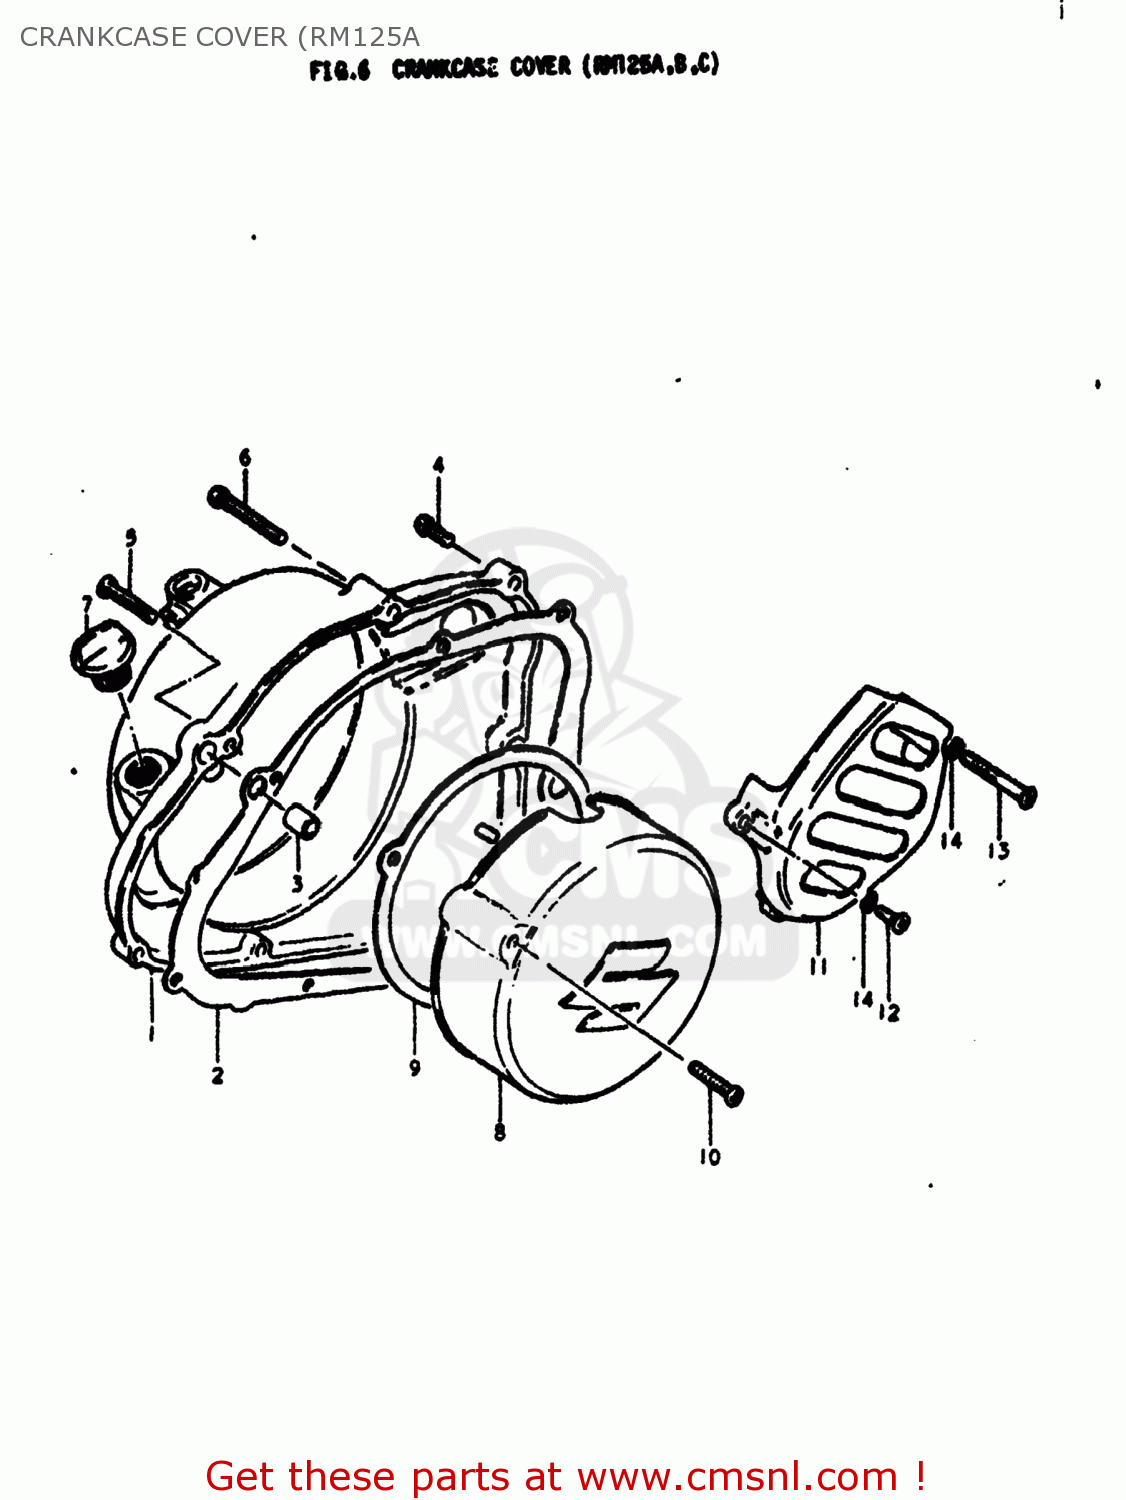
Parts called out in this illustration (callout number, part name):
1	COVER,CLUTCH
2	GASKET,CLUTCH COVER (AS (MCA)
3	PIN
4	SCREW
5	SCREW
6	SCREW (6X45)
7	PLUG,OIL FILTER
8	COVER
9	GASKET,MAGNETO COVER (NAS)
10	SCREW (6X45)
11	COVER,ENGINE SPROCKET
12	SCREW
13	SCREW
14	LOCK WASHER
